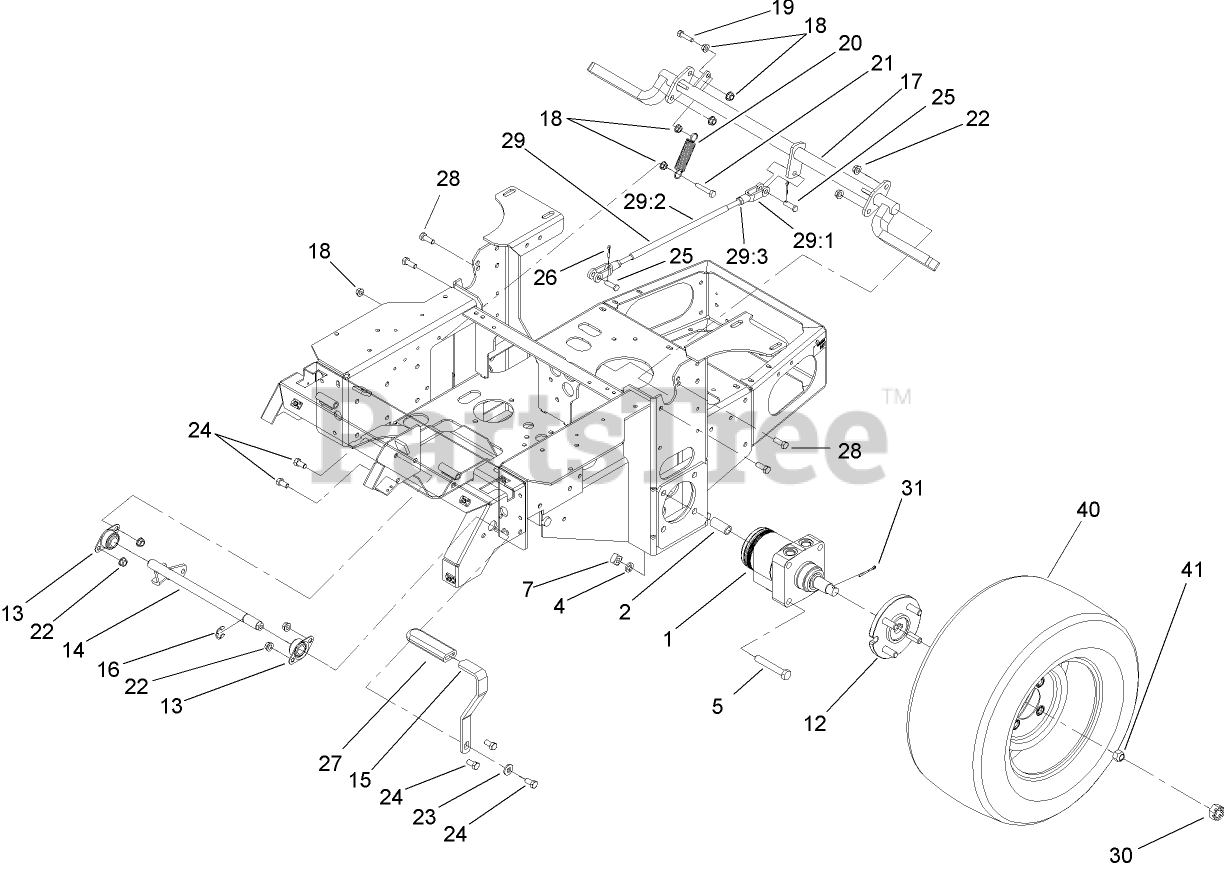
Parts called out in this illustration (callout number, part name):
1	MOTOR-WHEEL
2	SPACER-MOTOR, WHEEL
4	WASHER-LOCK
5	SCREW-HH
7	NUT-SQUARE
12	HUB ASM W/STUDS
13	BEARING-FLANGE, SIDE
14	Shaft-Brake, Parking
15	HANDLE-BRAKE, PARK
16	E-RING
18	NUT-HF
19	SCREW-HH
20	SPRING-IDLER
21	SCREW-HH
22	NUT-HHF, WHIZ
23	WASHER-BELLEVILLE
24	SCREW-HH
25	PIN-CLEVIS
26	PIN-COTTER
27	GRIP-LEVER
28	SCREW-HH
29	BRAKE ROD ASM
29:1	YOKE-LINKAGE, BRAKE
29:2	LINKAGE-HANDLE, BRAKE
29:3	NUT-HEX
30	NUT-HEX, SLOTTED
31	PIN-COTTER
40	WHEEL AND TIRE ASM
41	NUT-LUG
